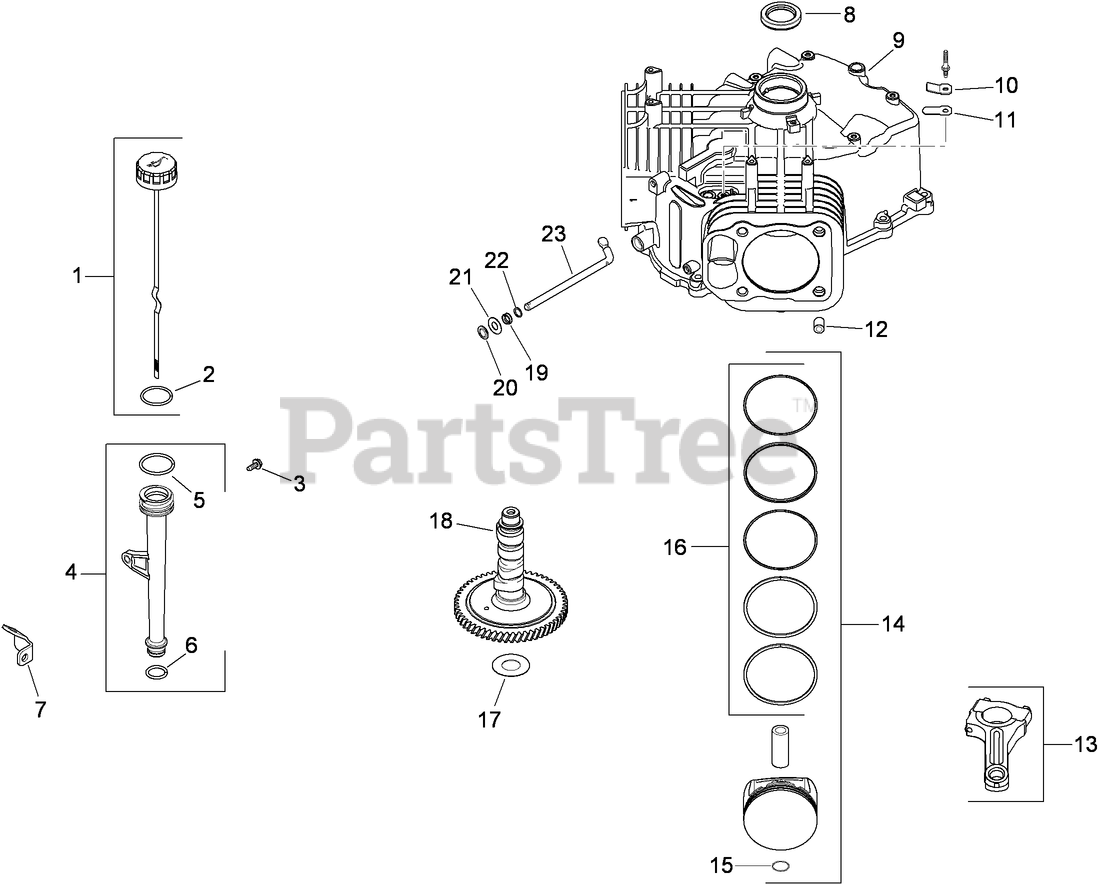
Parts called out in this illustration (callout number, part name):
1	Dipstick Kit (Includes?2)
2	O-RING
3	SCREW-FLG, THD FRM (M5X0.8X13)
4	OIL FILL TUBE ASM
5	O-RING
6	O-RING
7	BRACKET-TUBE, OIL FILL
8	SEAL-OIL (HELIX LIP)
9	SHORT BLOCK
10	RETAINER-REED, BREATHER
11	REED-BREATHER
12	PIN-LOCATING
13	ROD-CONNECTING (STD)
14	PISTON W/RING SET (STD) (INCLUDES REF 8, 17)
14	PISTON W/RING SET (.08) (USE 25 874 02-S KIT)
14	PISTON W/RING SET (.25) (INCLUDES REF 8, 19)
15	RETAINER-PIN, PISTON
16	PISTON RING SET (STD)
16	PISTON RING SET (.25)
17	SHIM-CAMSHAFT (WHITE .028)
17	SHIM-CAMSHAFT (BLUE .03)
17	SHIM-CAMSHAFT (RED .032)
17	SHIM-CAMSHAFT (YELLOW .034)
17	SHIM-CAMSHAFT (GREEN .036)
17	SHIM-CAMSHAFT (GRAY .038)
17	SHIM-CAMSHAFT (BLACK .04)
18	CAMSHAFT KIT (INCLUDES 25 357 14-S)
19	SEAL-CROSS SHAFT, GOVERNOR
20	RETAINER-RING
21	WASHER-FLAT (9MM)
22	WASHER-FLAT (11/32)
23	SHAFT-CROSS, GOVERNOR
